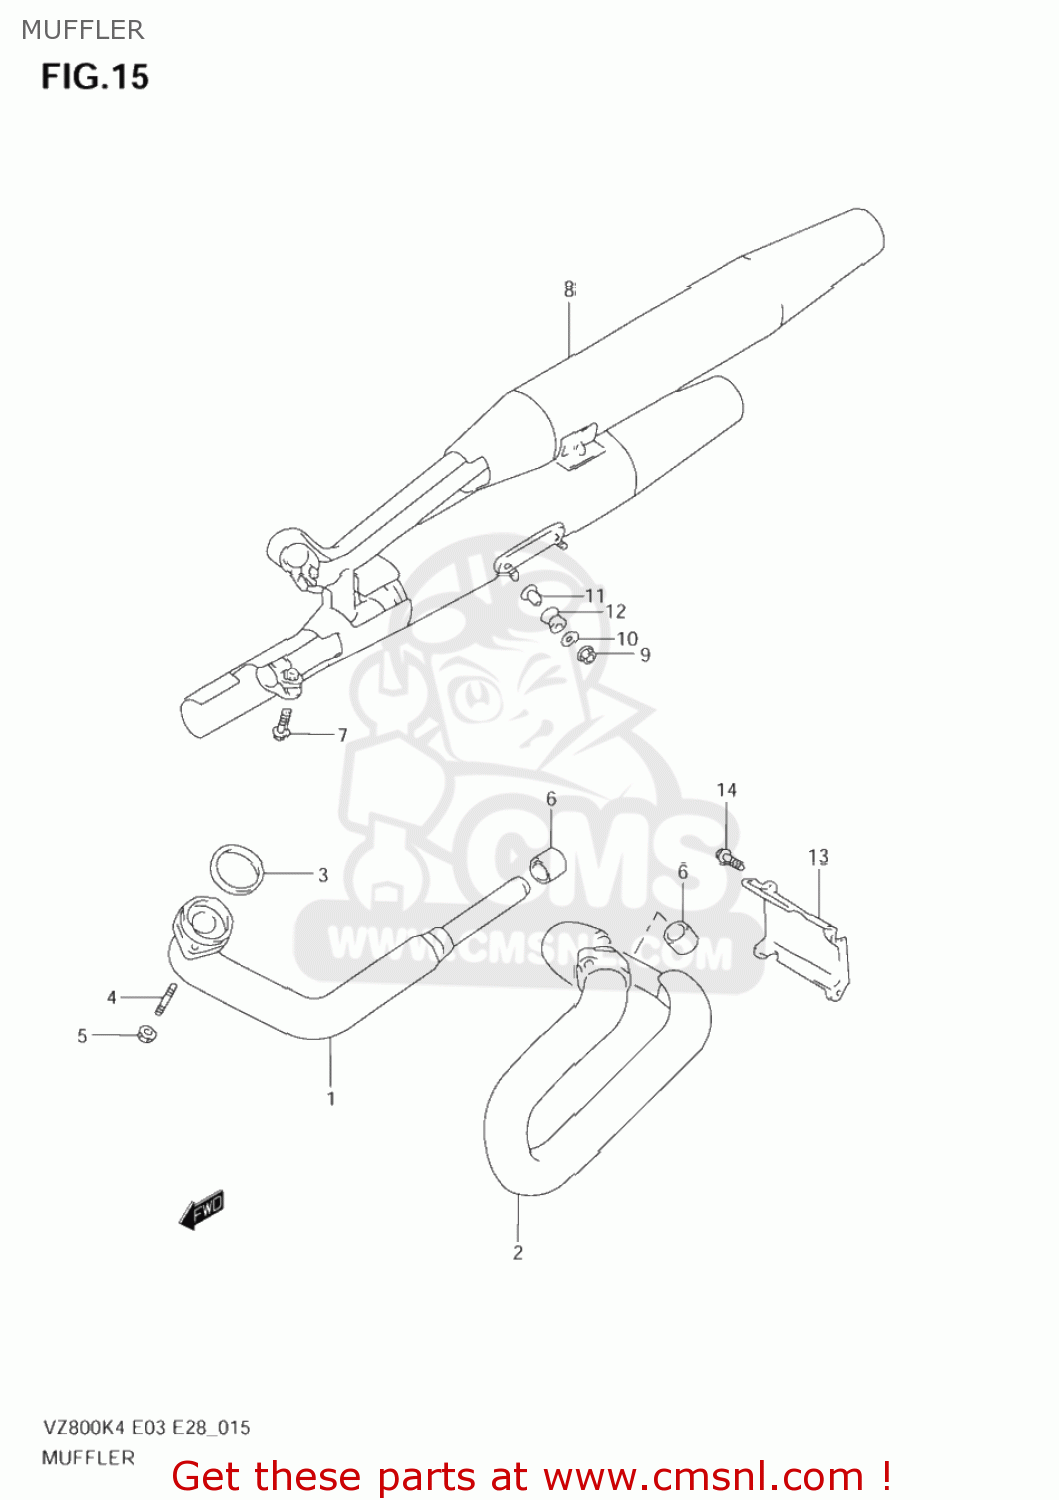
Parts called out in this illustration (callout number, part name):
1	PIPE,EXHAUST,R
2	PIPE,EXHAUST,L
3	GASKET,EXHAUST PIPE (NAS)
4	BOLT,STUD
5	NUT
6	CONNECTOR,MUFFLER JOINT
7	BOLT(8X33)
8	MUFFLER
9	NUT
10	WASHER (8.5X26X1.6)
11	SPACER(8.6X12X17.5)
12	CUSHION
13	GUARD,HEAT
14	BOLT
